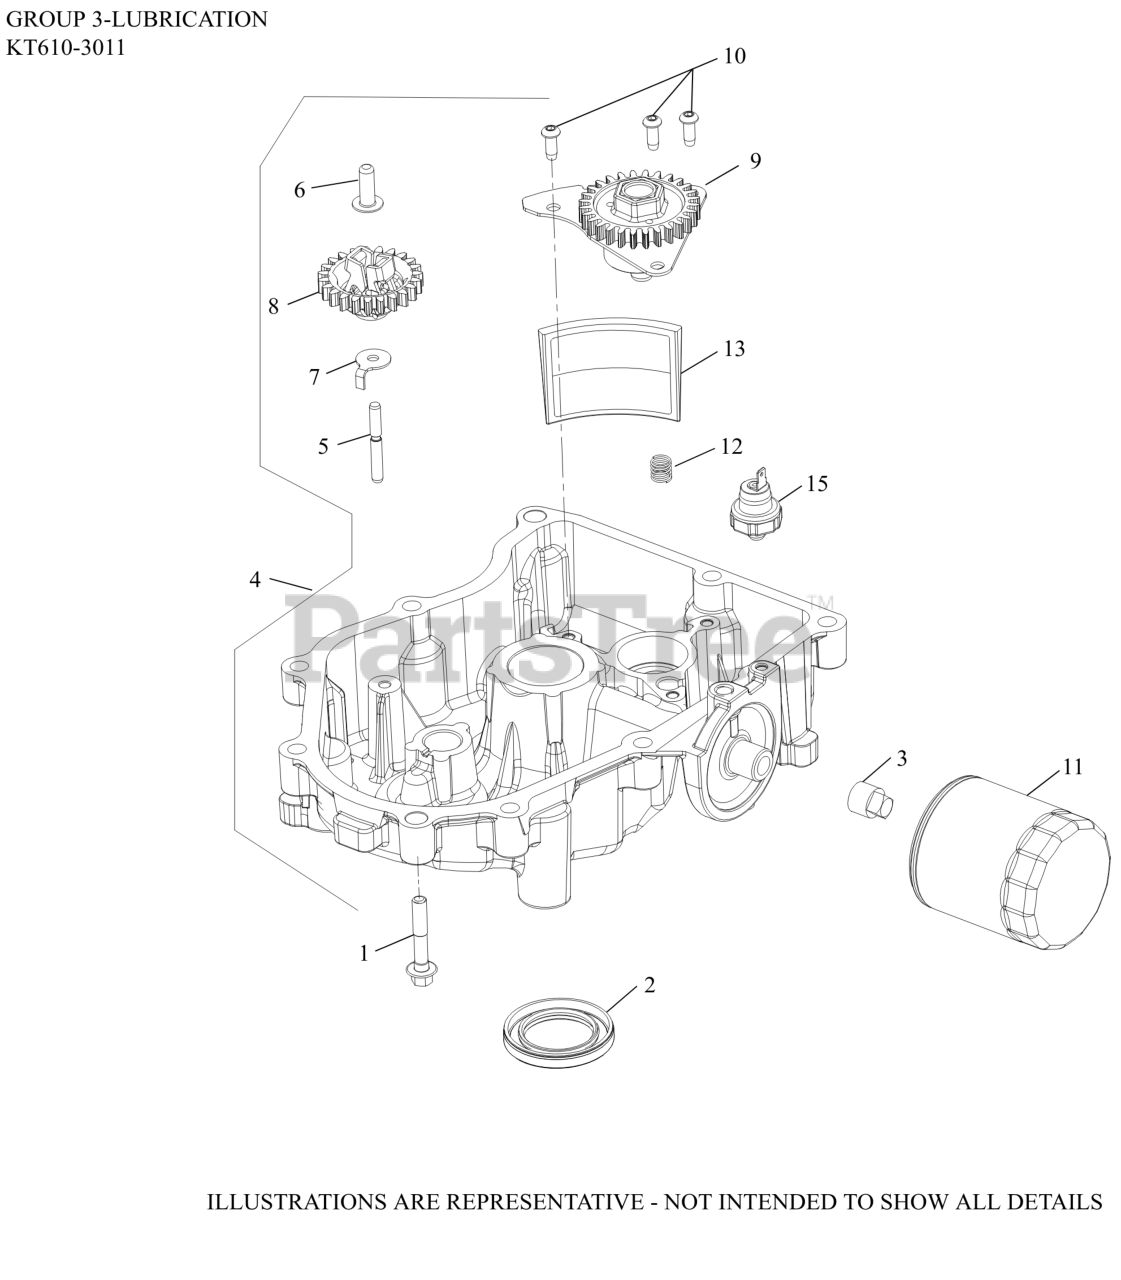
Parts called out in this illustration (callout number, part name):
1	SCREW, FLG M8X1.25X45
3	PLUG, SQ HD PIPE 3/8"
4	PAN ASSEMBLY, OIL-(#3219924S)
5	SHAFT, GOVERNOR GEAR
6	PIN, GOVERNOR REGULATING
7	TAB, LOCKING
8	KIT, GOVERNOR GEAR
9	PUMP ASSEMBLY, OIL
10	SCREW, BUTTON HEAD
11	OIL FILTER
12	SPRING, COMPRESSION
13	SCREEN, OIL
15	SENSOR, OIL PSI 3 TERMINAL
19	VALVE, OIL DRAIN MEDIUM
